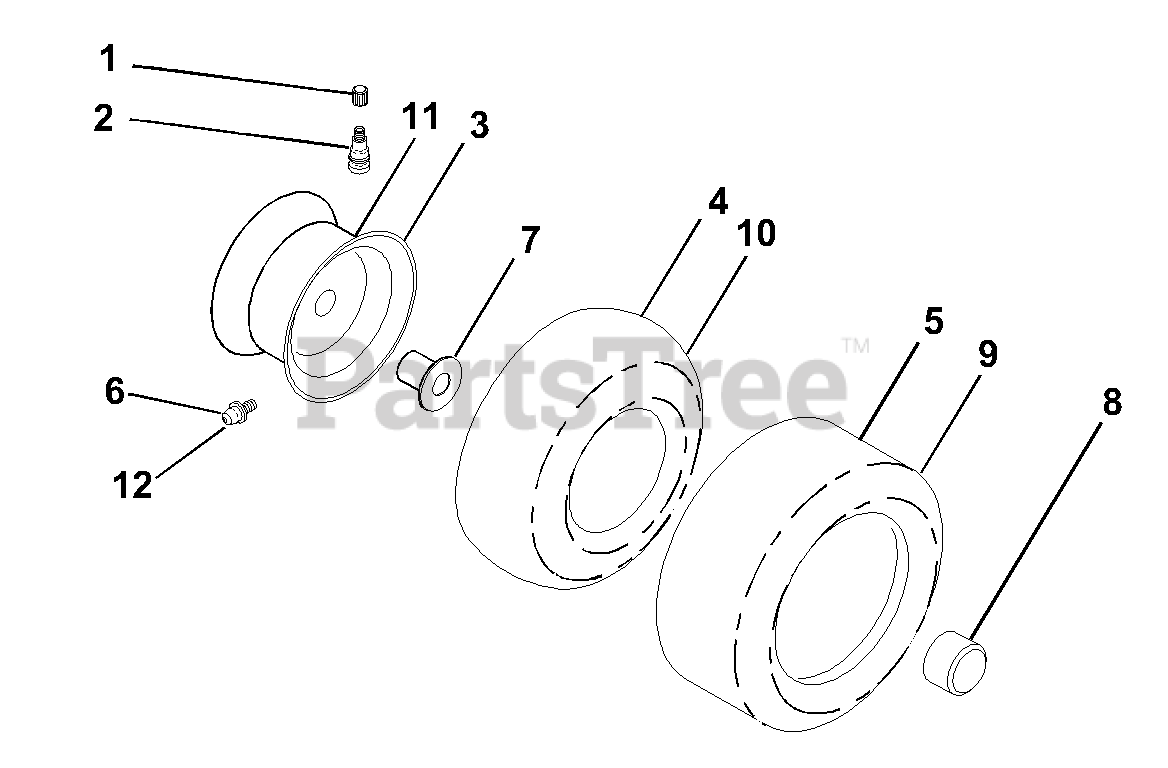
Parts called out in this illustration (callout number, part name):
1	Cap, Valve, Tire
2	Stem, Valve
3	Rim Assembly, Front
4	Tube, Front
5	Tire, Front
6	Fitting, Grease
7	Bearing, Flange
8	Cap, Hub, Axle Blk.
9	Tire,Rear
10	Tube, Rear
11	Rim Assembly, Rear
12	Fitting Grease
